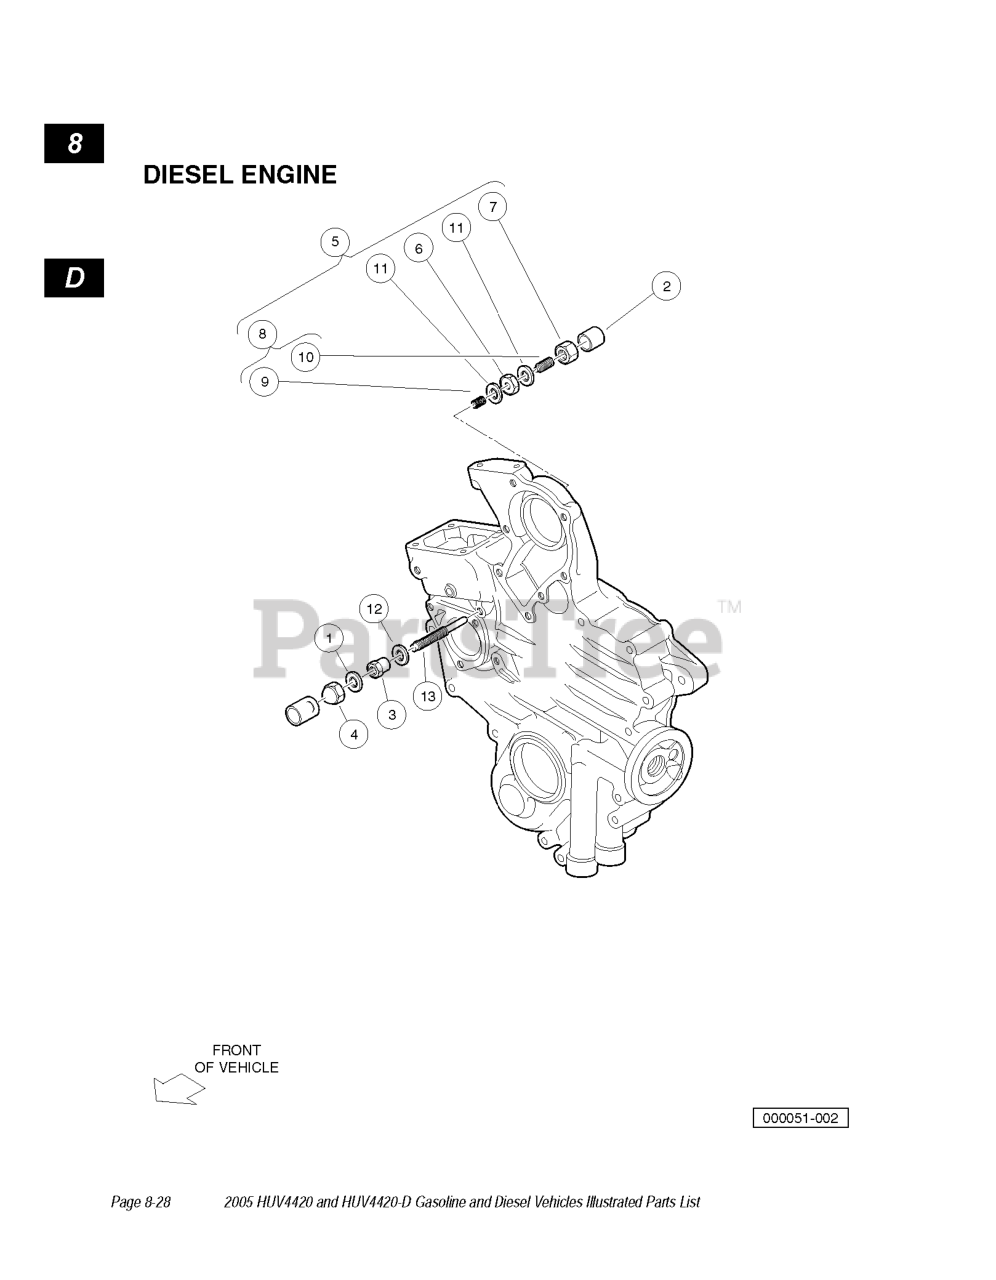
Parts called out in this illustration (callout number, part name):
1	GASKET, 6X10
2	CAP, BOLT ASSY
3	NUT, LOCK, SPECIAL
4	NUT, SPECIAL
5	ASSY,IDLE APPARATUS
8	SPRING, IDLE APPARATUS
11	GASKET, IDLE APPARATUS, REAR
12	GASKET, IDLE APPARATUS, FRONT
13	BOLT, IDLE ADJUSTING, D722 CB
